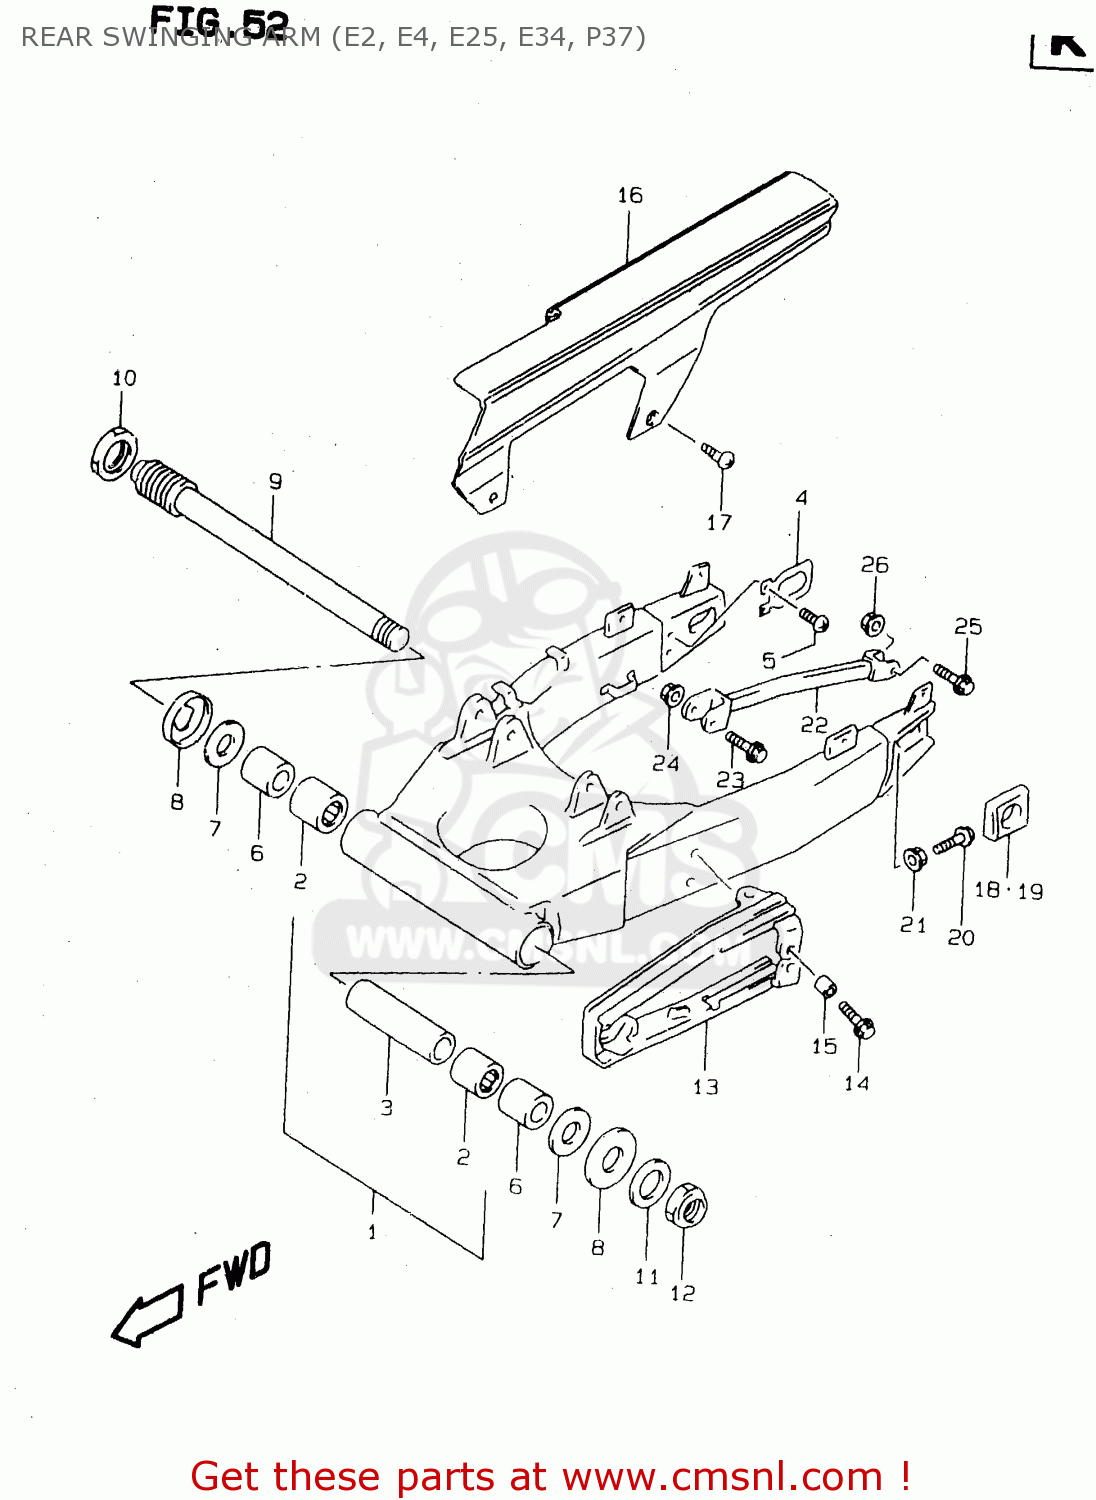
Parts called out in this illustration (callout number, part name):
1	SWINGINGARM ASSY,RR
2	BEARING(30X40X25)
3	SPACER COMP,REAR SWING PIVOT
4	PLATE,RR SWING ARM BRKT
5	SCREW 6X10
6	SPACER,REAR SWING ARM PIVOT
7	WASHER
8	DUST SEAL,RR SWGARM PIVOT
9	SHAFT,RR SWINGINGARM PIVOT
10	NUT,REAR SWING ARM PIVOT
11	WASHER(25.2X42X3.2)
12	NUT
13	BUFFER,CHAIN TOUCH DEFENSE
14	BOLT 6X20,WITH PLAIN WASHER
15	SPACER(6.5X9X5)
16	CASE,CHAIN
17	SCREW(6X16)
18	ADJUSTER,CHAIN,R
19	ADJUSTER,CHAIN,L
20	BOLT(8X50)
21	NUT
22	TORQUELINK,RR
23	BOLT(8X44)
24	NUT
25	BOLT(10X37)
26	NUT
